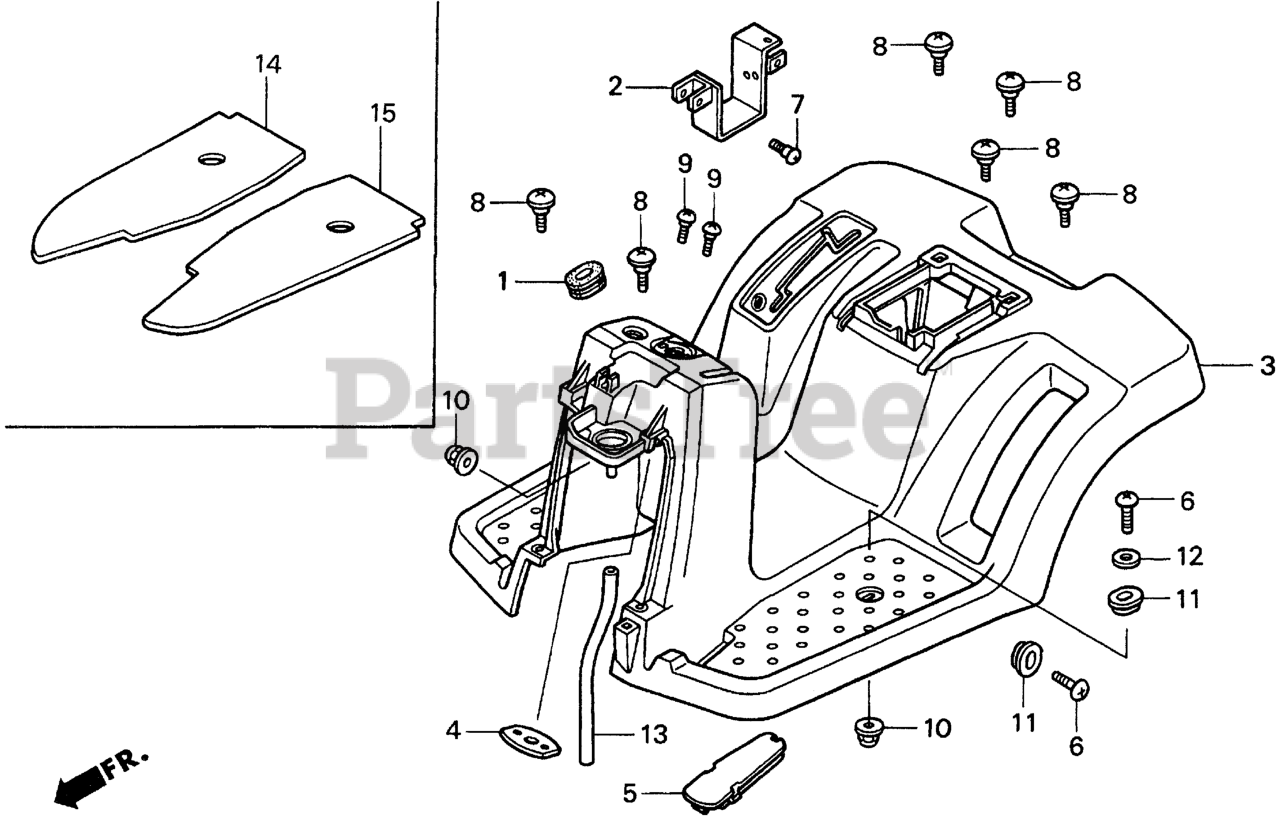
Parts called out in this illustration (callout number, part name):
1	RUBBER, FR. TANK
2	PLATE, NEUTRAL SWITCH
3	PLATFORM *R165* (JOLLY RED)
4	PLATE, STEERING SHAFT
5	LID, PEDAL HOLE *R165* (JOLLY RED)
6	SCREW, TORUS (6X20)
7	SCREW, SPECIAL (5MM)
8	SCREW, SIDE COVER SETTING
8	SCREW, PLATFORM SETTING
9	SCREW, PAN (5X15)
10	NUT, SELF-LOCK (6MM)
11	WASHER (6X9)
12	WASHER, PLAIN (6MM)
13	BULK HOSE, VACUUM (12X1000) (12X340)
14	FLOOR MAT, R.
15	FLOOR MAT, L.
NI	FLOOR MAT SET
